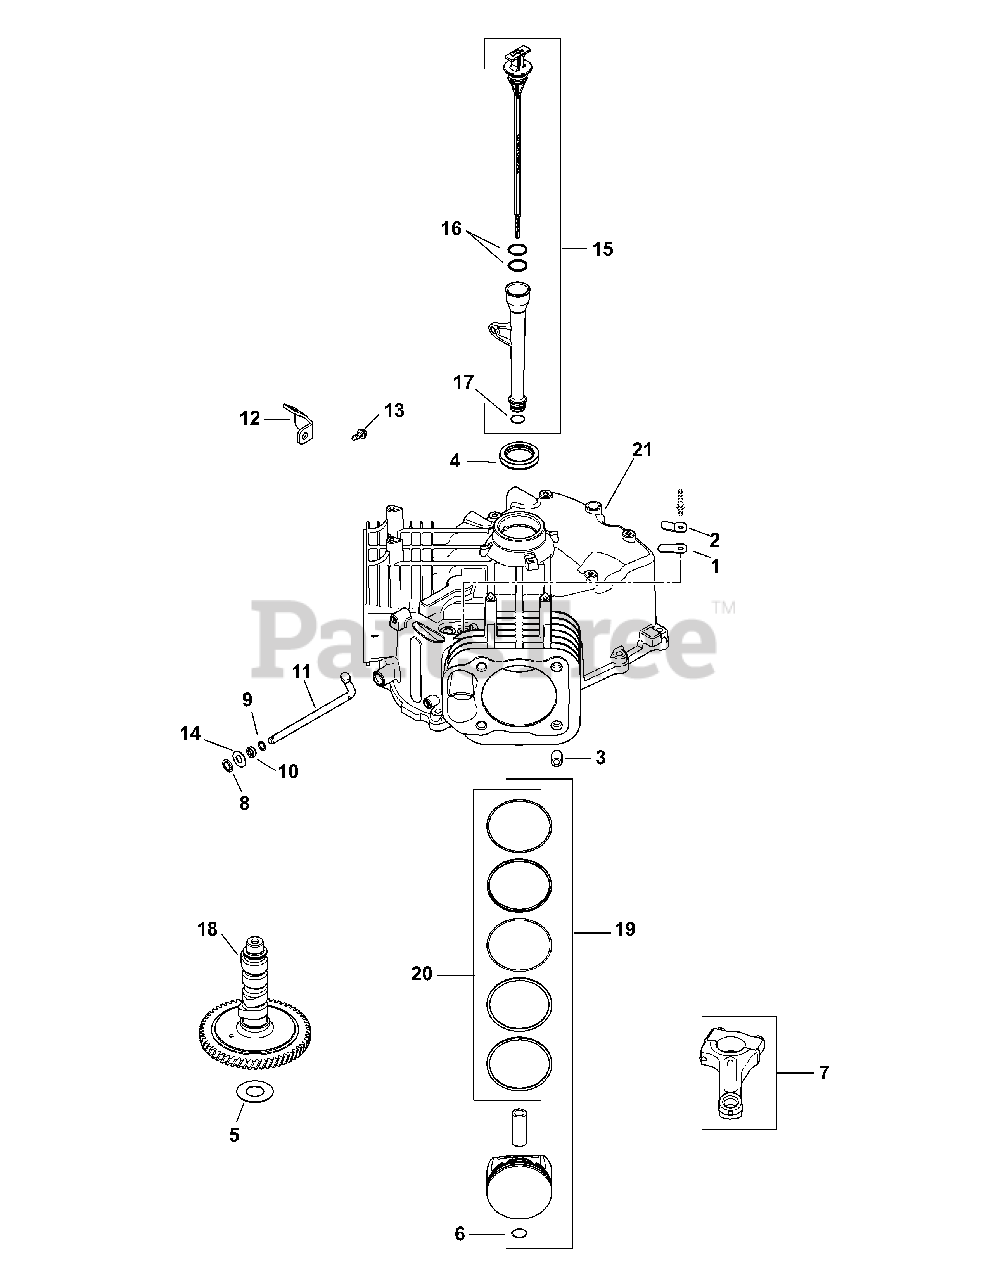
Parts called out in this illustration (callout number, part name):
1	Breather Reed
2	Breather Reed Retainer
4	Oil Seal, 1.78 x 1.26
5	Camshaft Shim (White, .028)
5	Camshaft Shim (Blue, .03)
5	Camshaft Shim (Red, .032)
5	Camshaft Shim (Yellow, .034)
5	Camshaft Shim (Green, .036)
5	Camshaft Shim (Gray, .038)
5	Camshaft Shim (Black, .04)
6	Piston Pin Retainer
7	Connecting Rod (STD)
8	Ring Retainer
9	Flat Washer, 11/32
10	Governor Cross Shaft Seal
11	Governor Cross Shaft
12	Oil Fill Tube Bracket
13	Flange Screw, M5 x .8 x 13
14	Flat Washer, 9mm
15	Dipstick & Tube Kit
17	Lower Oil Fill Tube O-Ring
18	Camshaft Assembly
19	Piston W/ Ring Kit (STD)
20	Ring Set (STD)
21	Crankcase (Use Short Block)
